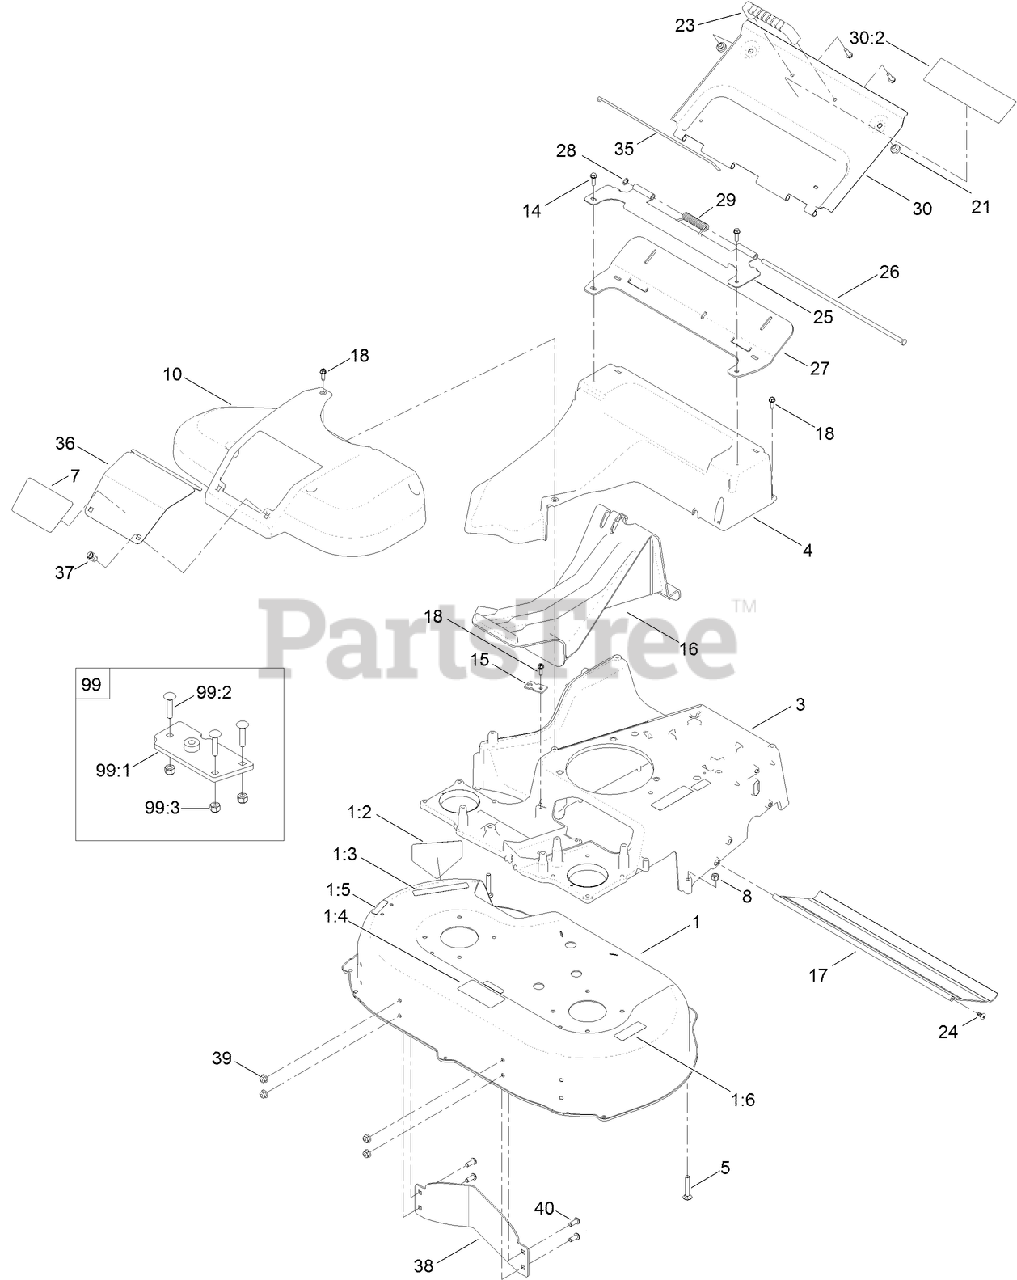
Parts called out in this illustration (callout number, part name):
1	DECK ASM
1:2	DECAL-DANGER
1:3	DECAL-DANGER
1:5	DECAL-WARNING
1:6	DECAL-WARNING, BLOCK
3	FRAME
4	CHUTE
5	SCREW-CARR
8	NUT-LOCK, NI
10	COVER-BELT
14	SCREW-HWH
15	BRACKET-CABLE, TRACTION
16	PLUG-MULCH
17	SHIELD-TRAILING
18	SCREW-HWHTF
21	BUMPER
23	HANDLE-DOOR
24	SCREW-PTH
25	BRACKET-HINGE
26	PIN-HINGE
27	SEAL-DOOR
28	RING-RETAINING
29	SPRING-TORSION, COVER
30	REAR DOOR ASM
30:2	DECAL-WARNING
35	CLIP-SEAL
36	DOOR-ACCESS
37	FASTENER
38	BAFFLE-FLOW, CONTROL
39	NUT-HF, NI
40	SCREW-HSBH
99	FRAME PLATE KIT
99:1	PLATE-FRAME
99:2	SCREW-CARR
99:3	NUT-LOCK, NI
